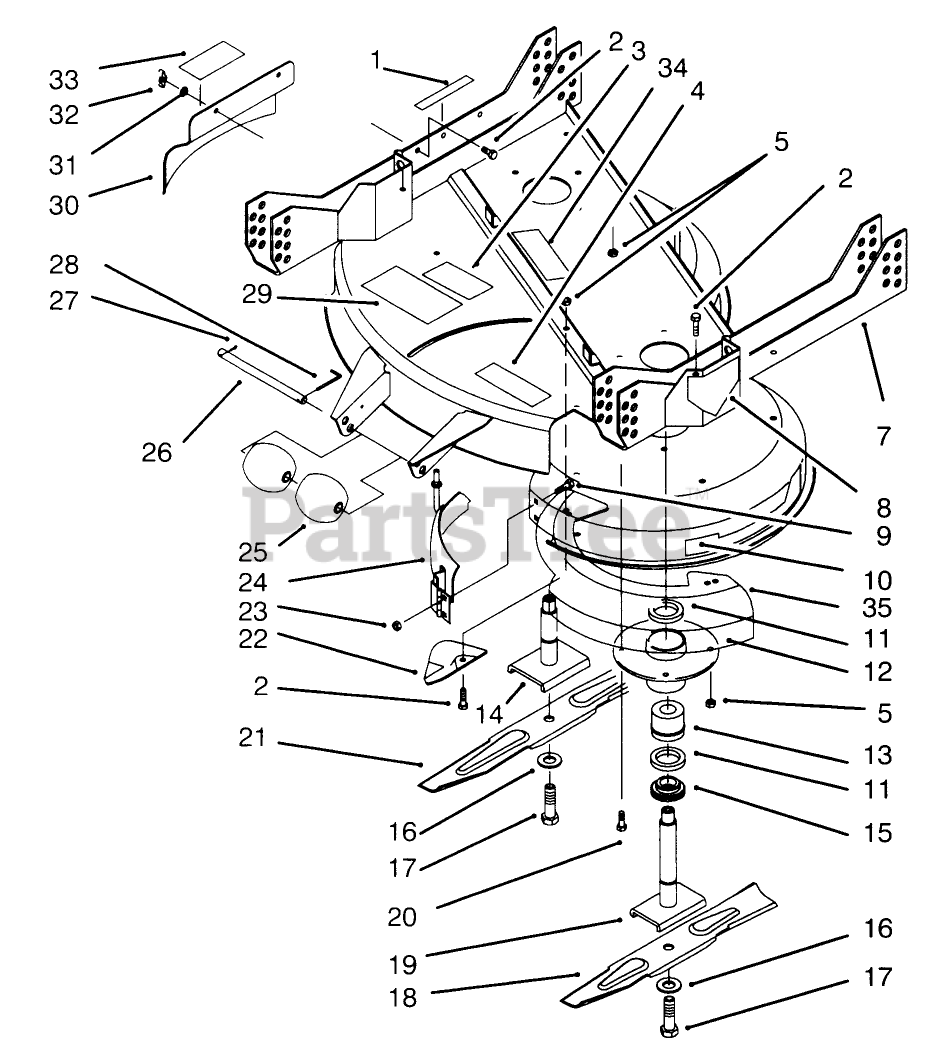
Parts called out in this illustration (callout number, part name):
1	Spacer
2	SCREW-HH
3	Spacer
4	Spacer
5	NUT-LOCK, NI
7	Bar-Control
8	Spacer
9	SCREW-CARRIAGE
10	Spacer
11	SEAL-OIL
12	SPINDLE HOUSING
13	BEARING ASM
14	SHAFT-SPINDLE
15	SPACER
16	WASHER-LOCK
17	SCREW-BLADE
18	Blade
19	SHAFT-SPINDLE
20	SCREW-HH
21	Blade
22	PLATE-KICKER
23	NUT-KEPS
24	Cover-Front
25	ROLLER
26	SHAFT-ROLLER
27	PIN-COTTER
28	PIN-SPECIAL
29	Spacer
30	Cover-Discharge
31	WASHER-LOCK
32	NUT-WING
33	Spacer
34	Spacer
35	Insert-Deck
